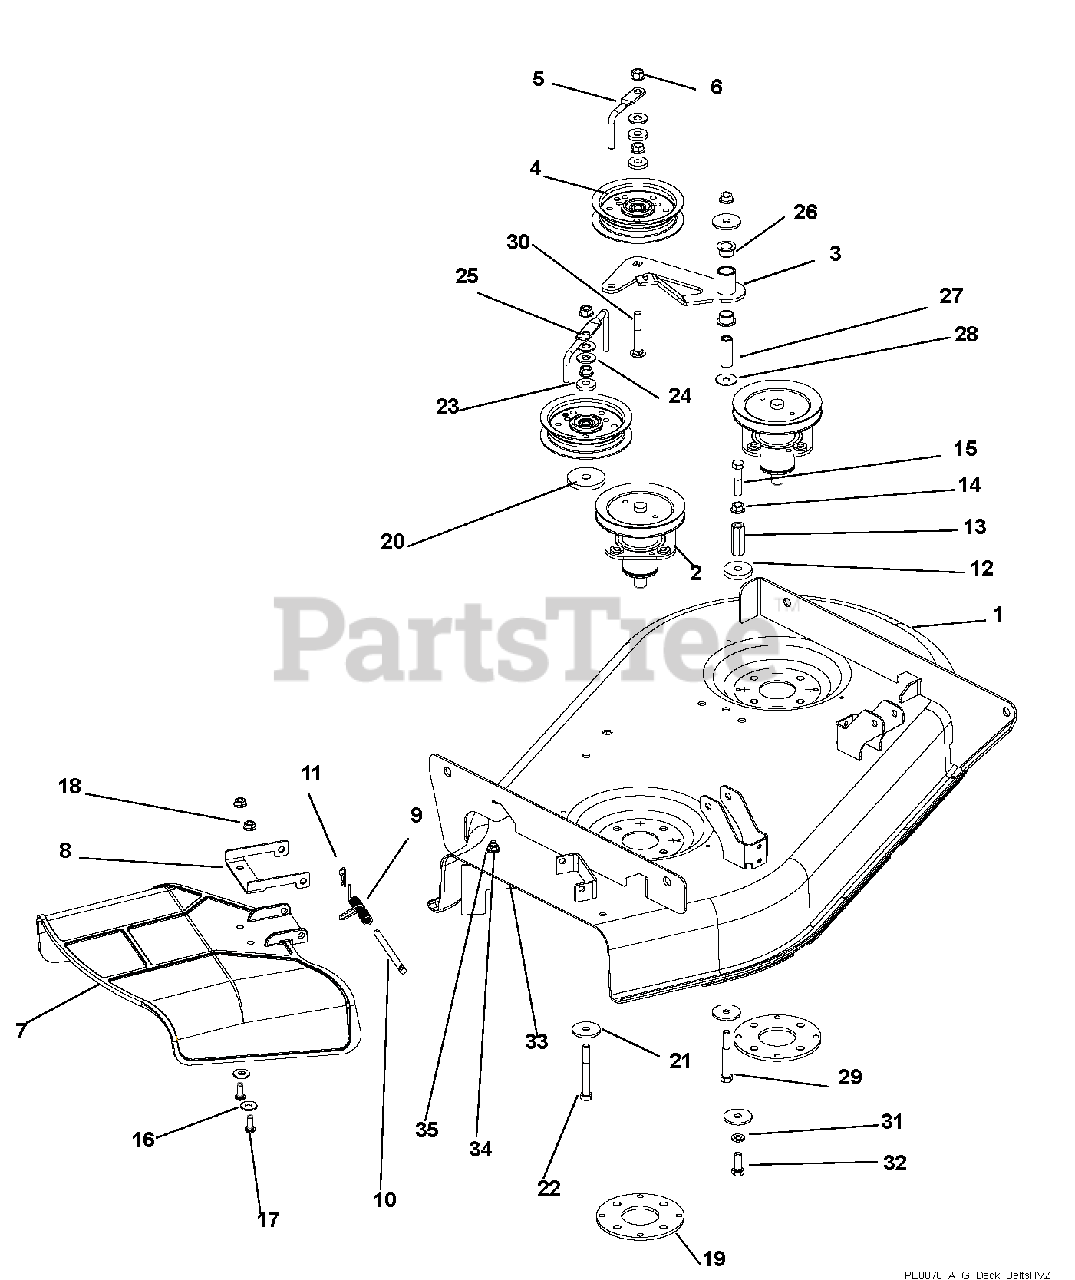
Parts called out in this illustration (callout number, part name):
1	WMT, 34" DECK
2	KIT, DECK SPINDLE ASM (34/50)
3	WMT, IDLER ARM
4	ASM, IDLER 4"
5	WIREFORM, BELT FINGER
6	@NUT-LK-TOP-FLG .38-16 YWZC
7	CHUTE, SIDE DISCHARGE
8	CHUTE REINFORCEMENT
9	SPRING, TORSION
10	PIN, 5/16 X 3.88"
11	PIN-HAIR INT .08X.18X1.18 YWZC
12	WSHR,FLT STL.406X1.50X.245YWZC
13	NUT COUPLING .375-16X1.75
14	@NUT-SPNLK-FLG .375-16 YWZC
15	@BLT-HEX .38-16X1.75 GR5 YWZC
16	@WSHR-FL-STL.38X.875X.083 YWZC
17	SCR-SKH .31-18X.75 BTNHD YWZC
18	@NUT-LK-TOP-FLG .31-18 YWZC
19	PLATE-REINF, SPINDLE
20	WSHR-FL-STL .469X2.00X.25 YWZC
21	WSHR-FL-STL .380X1.50X.125YWZC
22	@BLT-HEX .38-16X3.00 GR5 YWZC
23	WSHR-FL-STL .406X1.00X.188 YWZ
24	@WSHR-FL-STL.438X1.00X.083 YWZ
25	WIREFORM, BELT FINGER
26	BSHG-FLG, .625X.750X.500X1.00
27	SPACER, .375IDX.625ODX1.66 PM
28	WSHR-FL-STL .375X1.125X.065YWZ
29	@BLT-HEX .38-16X2.75 GR5 YWZC
30	@BLT-RDHDSQNK .38-16X2.50 G5YZ
31	@WSHR-LK .38X.094 REG YWZC
32	@BLT-HEX .38-16X1.00 GR5 YWZC
33	BRKT-BAFFLE, DISCHARGE 34"
34	@BLT-HEX .31-18X.75 GR5 YWZC
35	@NUT-LK-NYL-FLG .31-18 YWZC
